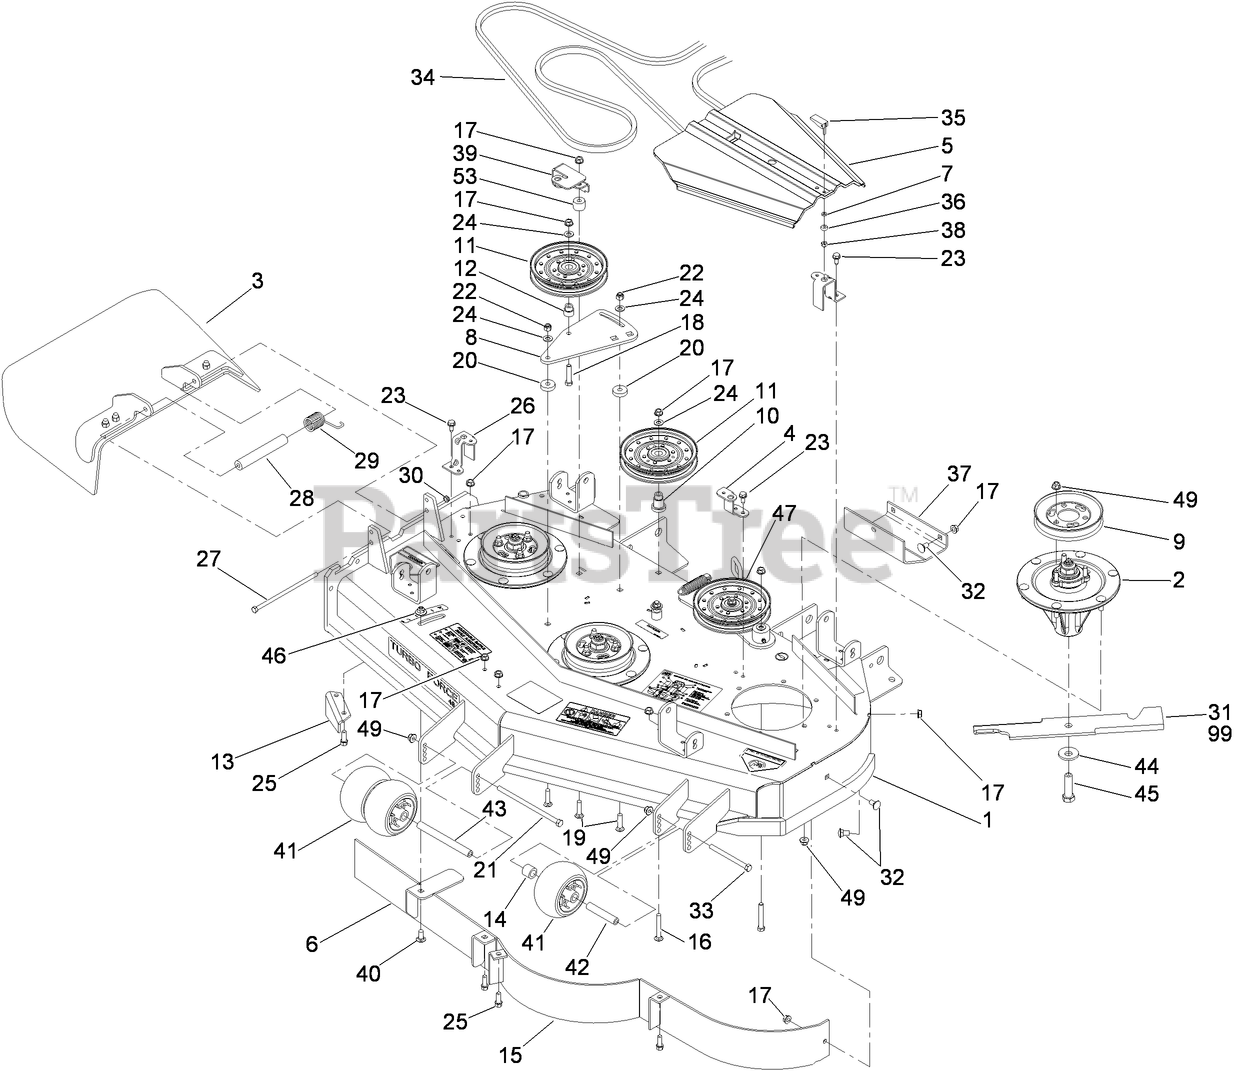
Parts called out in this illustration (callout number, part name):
1	DECK DECAL ASM
2	SPINDLE ASM
3	RUBBER DEFLECTOR ASM
4	BRACKET-COVER, TALL
5	COVER-BELT
6	BAFFLE ASM
7	WASHER
8	PLATE - IDLER
9	PULLEY
10	MOUNT-PULLEY
11	Idler-Flat
12	BUSHING-IDLER
13	BAFFLE-DISCHARGE
14	TUBE-SPACER
15	BAFFLE ASM
16	SCREW-CARR
17	NUT-HHF, WHIZ
18	SCREW-HH
19	SCREW-CARR
20	Spacer
21	SCREW-HH
22	NUT-LOCK, NI
23	SCREW-HWHTF
24	WASHER-FLAT
25	SCREW-HWH
26	BRACKET-COVER
27	SCREW-HH
28	SPACER
29	SPRING-TORSION
30	NUT-LOCK, NI
31	BLADE-16.5 INCH (HIGH FLOW)
32	SCREW-CARR
33	SCREW-HH
34	BELT-V
35	HANDLE-LATCH, SWELL
36	BUSHING-LATCH, SWELL
38	NUT-LOCK, HH
39	BRACKET - COVER
40	SCREW-CARR
41	ROLLER-SCALP, ANTI
42	TUBE-SPANNER
43	SPACER-WHEEL
44	Washer-Blade Bolt, Heavy
45	SCREW-BLADE
46	NUT-FLANGE, NI
47	SPRING IDLER ASM
49	NUT-HF, NI
53	SPACER
99	BLADE-RECYCLER, 16.5 INCH
99	BLADE-ROTARY, 16.5 INCH (ATOMIC)
99	BLADE-ROTARY, 16.5 INCH (MED FLOW)
99	BLADE-ROTARY, 16.5 INCH (LOW FLOW)
